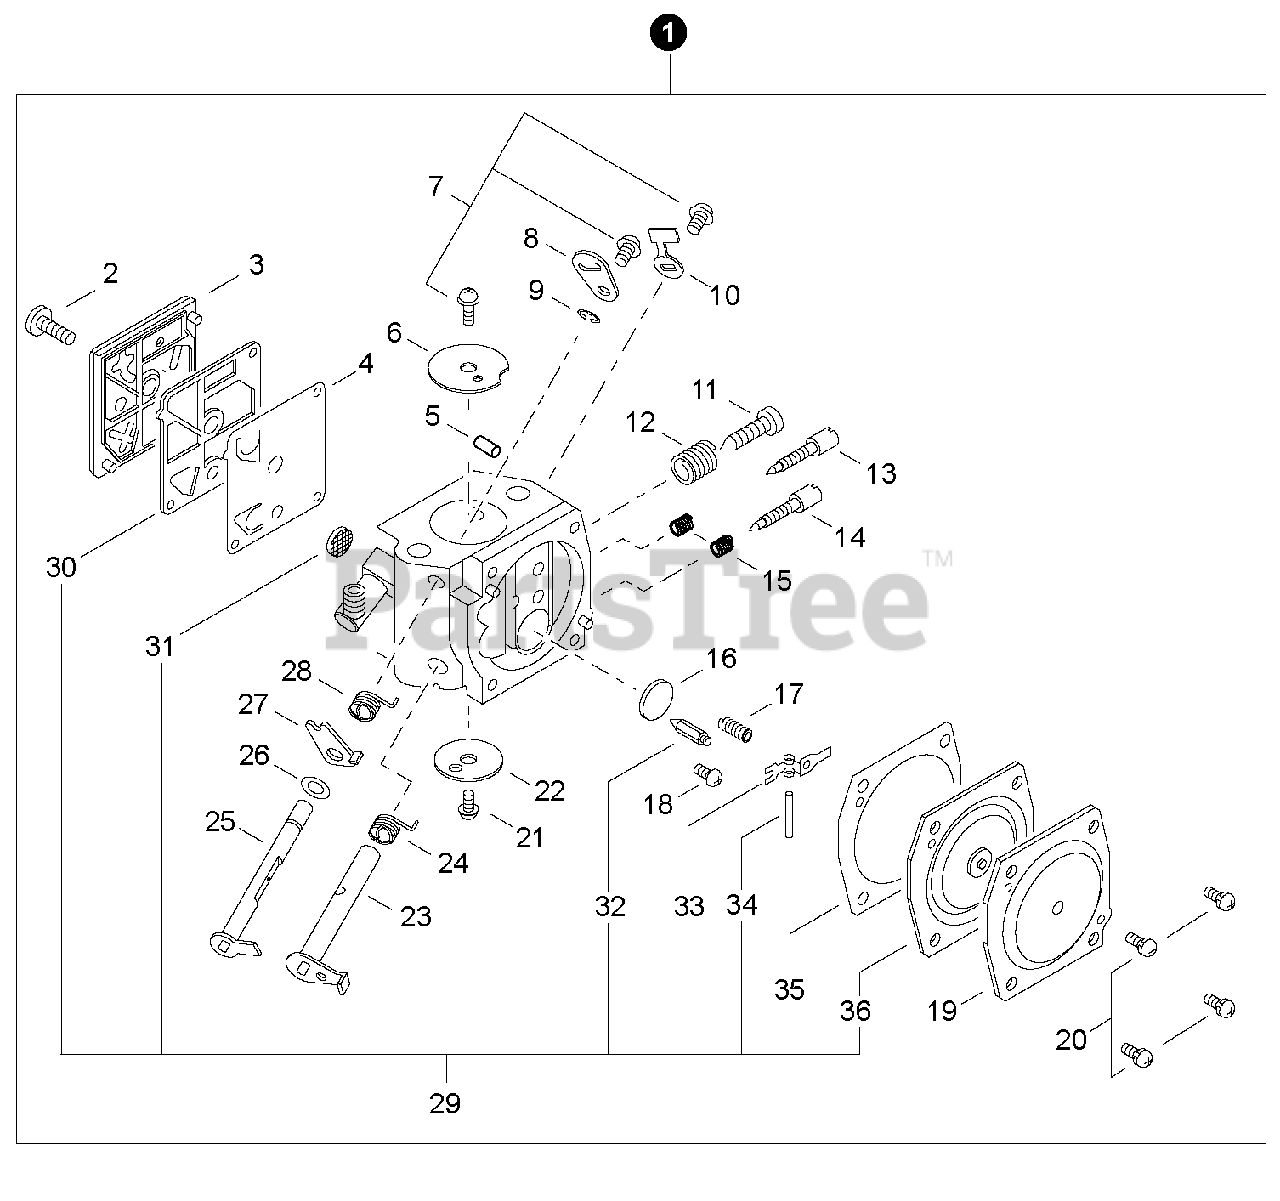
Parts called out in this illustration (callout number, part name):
1	CARBURETOR - HDA-257A
3	COVER, FUEL PUMP
4	DIAPHRAGM, FUEL PUMP
5	PLUG, FRICTION
6	VALVE, CHOKE
8	LEVER, CHOKE
10	STOP, THROTTLE
11	SCREW, IDLE ADJUST
13	NEEDLE, HIGH SPEED
14	NEEDLE, IDLE
15	SPRING, NEEDLE
16	PLUG, WELCH
18	SCREW, METERING LEVER PIN
19	COVER, METERING DIAPHRAGM
22	VALVE, THROTTLE
23	SHAFT ASSY, THROTTLE
24	SPRING, THROTTLE RETURN
25	SHAFT ASSY, CHOKE
27	LEVER, FAST IDLE
28	SPRING, CHOKE RETURN
29	REPAIR KIT
30	GASKET, FUEL PUMP
32	VALVE, INLET NEEDLE
33	LEVER, METERING
34	PIN, METERING LEVER
35	GASKET, METERING
36	DIAPHRAGM, METERING
